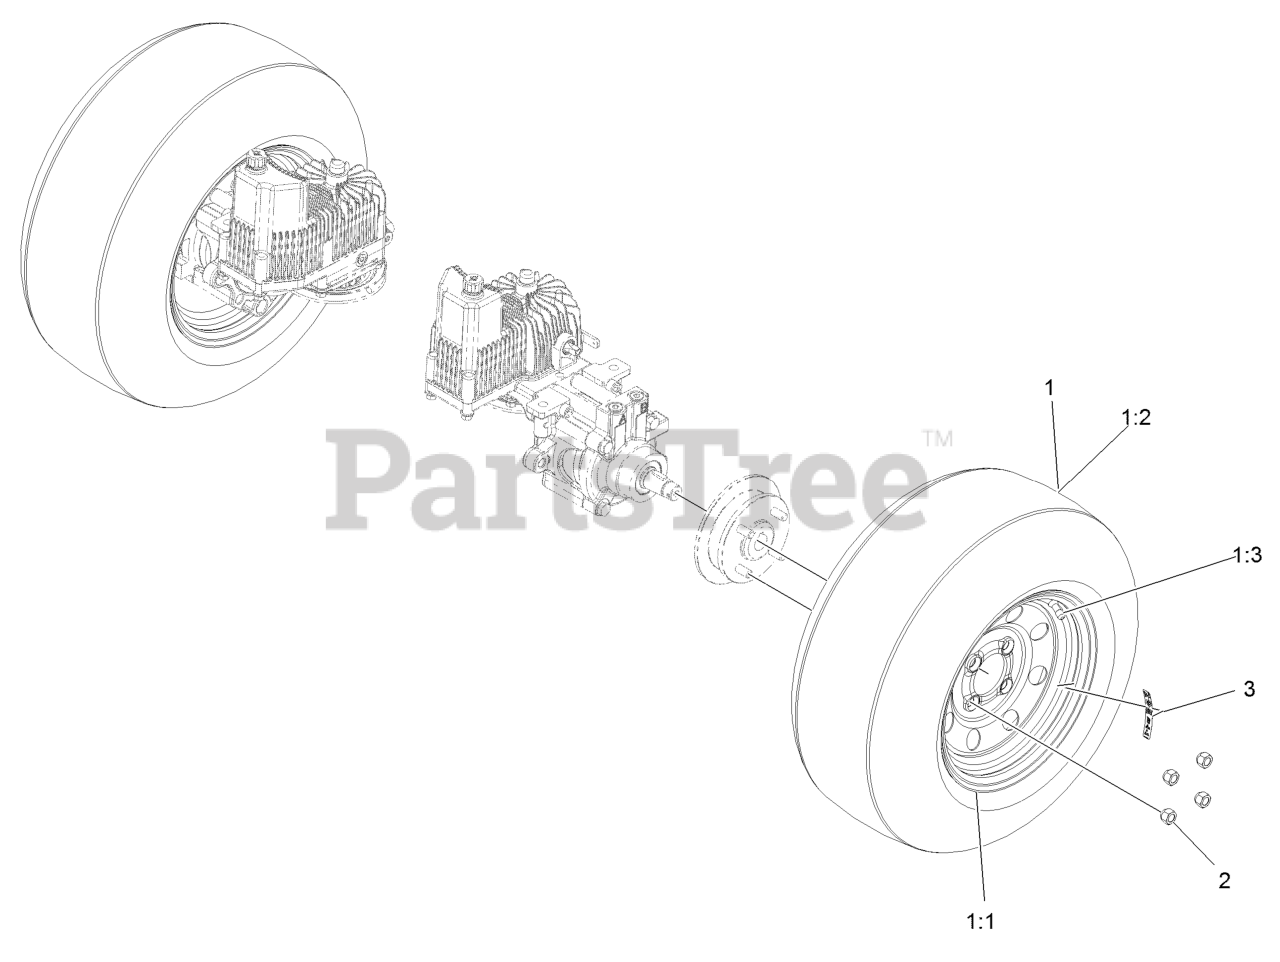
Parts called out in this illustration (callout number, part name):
1	WHEEL AND TIRE ASM
1:1	ASM, RIM
1:2	TIRE-DRIVE, 23X9.5-12
1:3	Stem-Valve
2	NUT-LUG
3	DECAL-TORQUE, WHEEL HUB LUG
